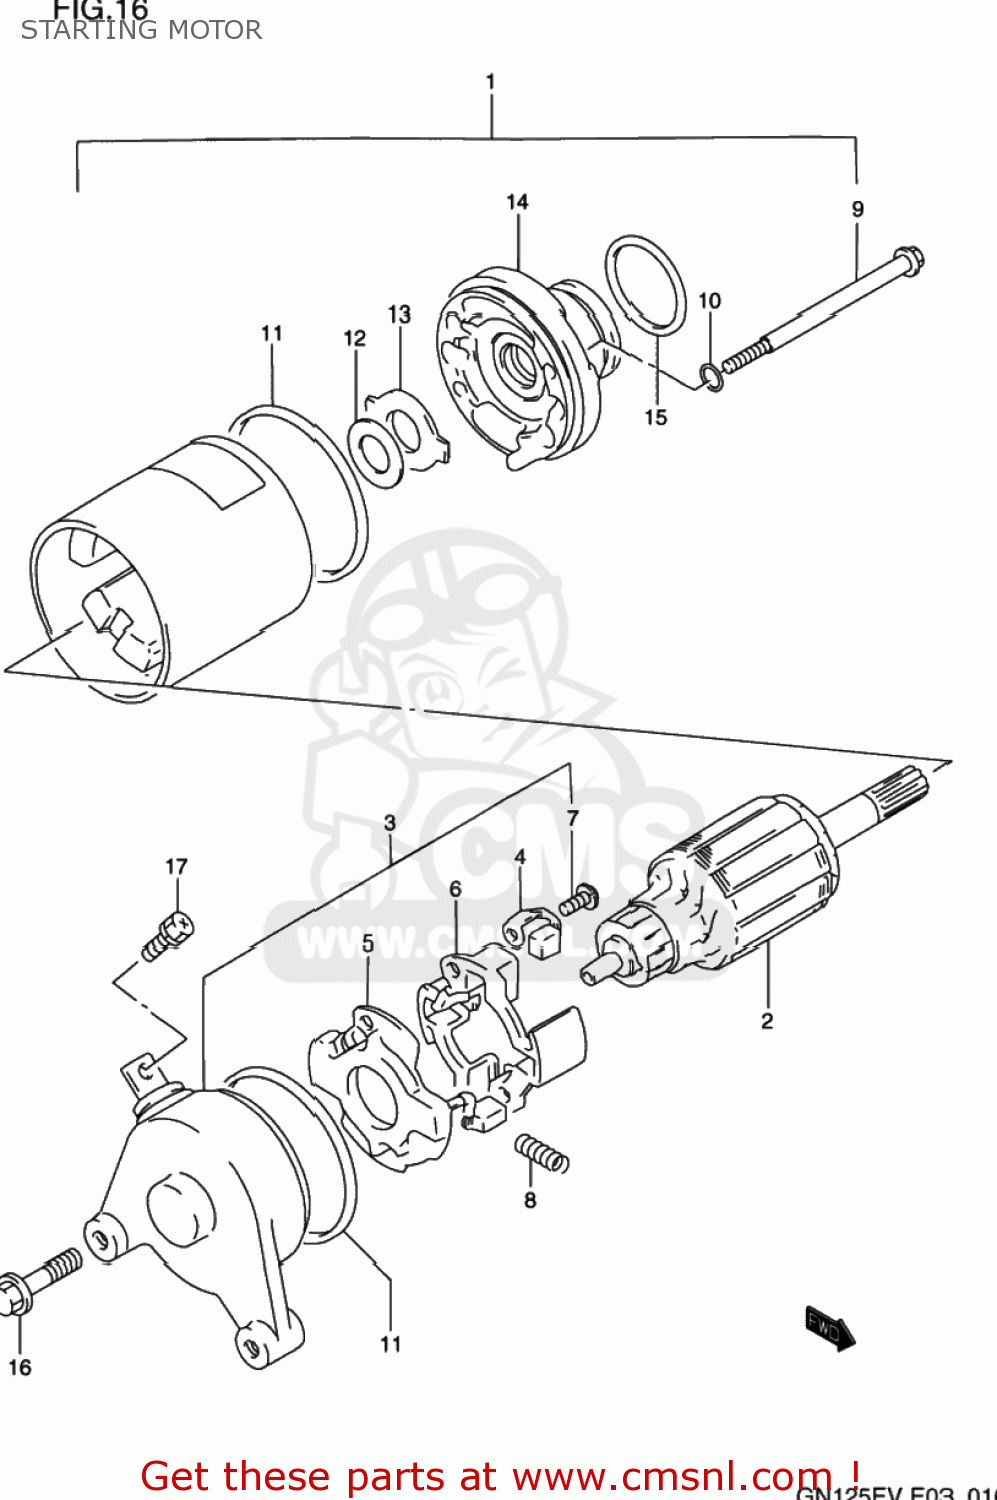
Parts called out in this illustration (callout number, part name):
1	MOTOR ASSY,STARTING
2	ARMATURE
3	FRAME ASSY,COMMUTATOR END
4	BRUSH
5	BRUSH SUB ASSY,STARTER
6	HOLDER,BRUSH
7	SCREW
8	SPRING
9	BOLT
10	O RING
11	O RING
12	SHIM
13	PLATE,LOCK
14	BRACKET
15	O RING(D:3,ID:24.5)
16	BOLT
17	SCREW(5X8)
